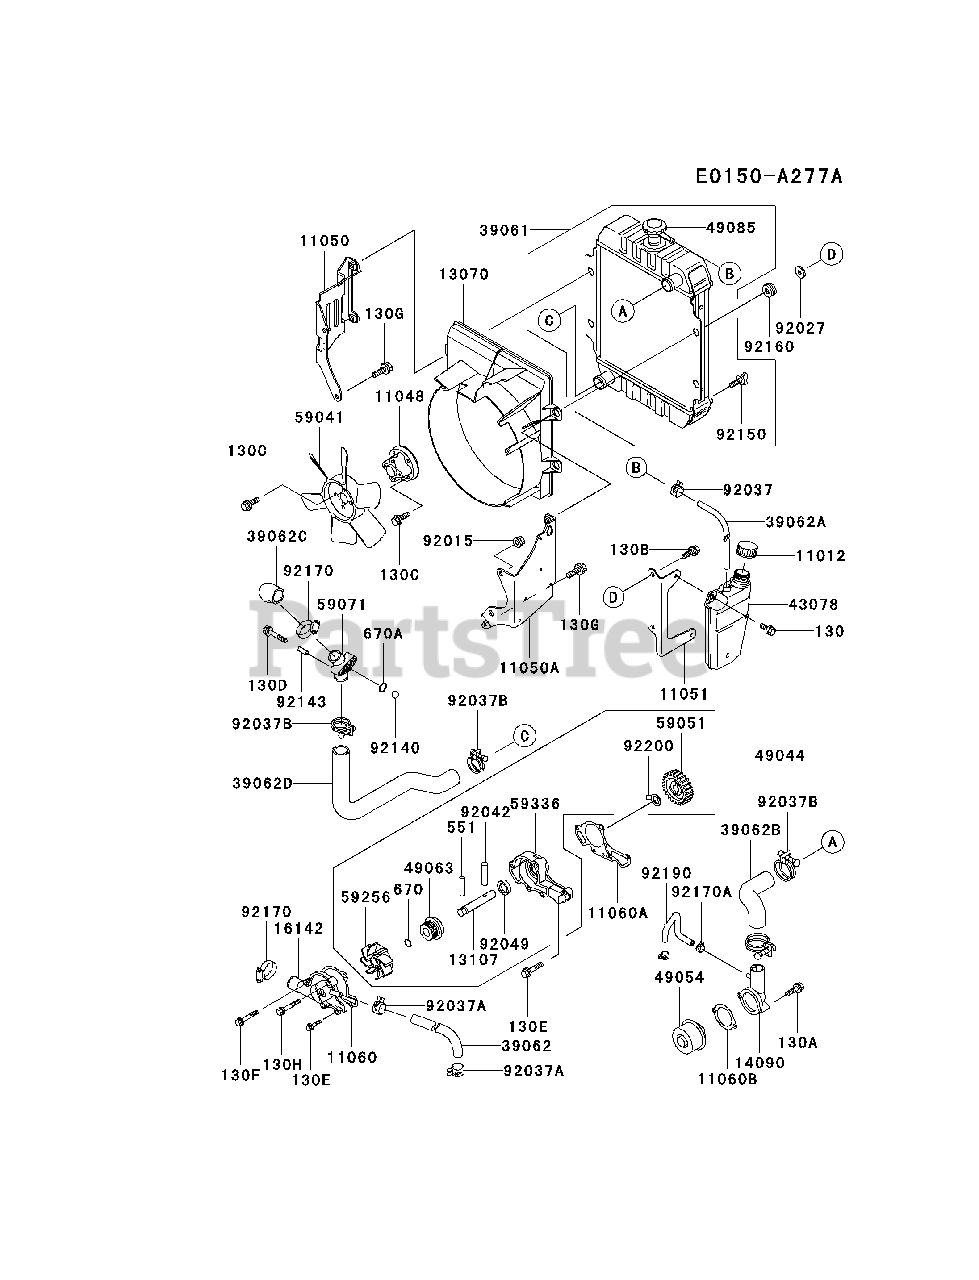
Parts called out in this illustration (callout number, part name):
130	BOLT-FLANGED
130A	BOLT-FLANGED
130B	BOLT-FLANGED
130C	BOLT-FLANGED
130D	BOLT-FLANGED
130E	BOLT-FLANGED
130F	BOLT-FLANGED
130G	BOLT-FLANGED
130H	BOLT-FLANGED
551	PIN-DOWEL
670	O RING
670A	O RING
